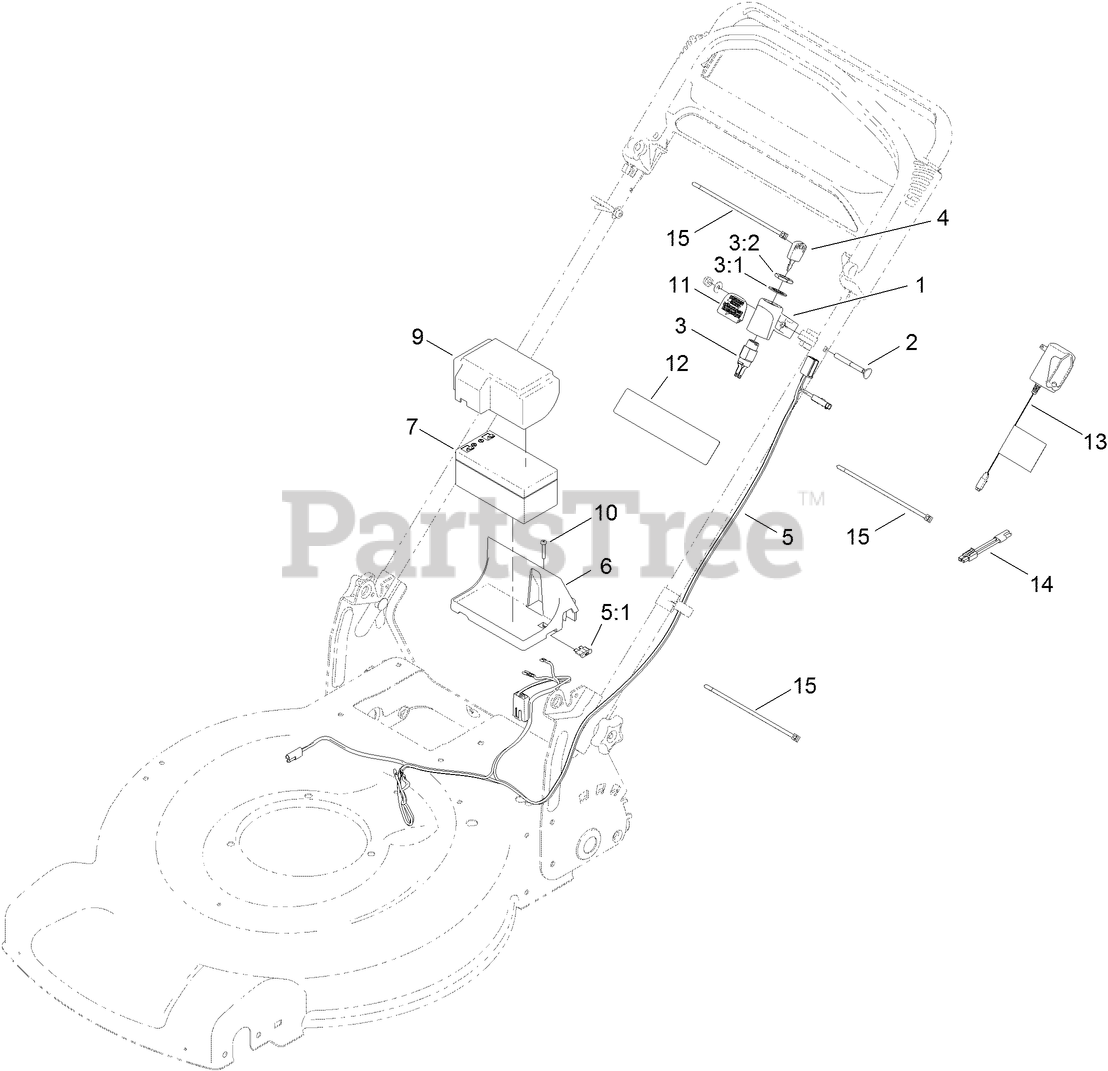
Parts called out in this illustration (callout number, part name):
1	MOUNT-SWITCH
2	SCREW-HANDLE
3	STARTER SWITCH ASM
3:1	WASHER-LOCK
3:2	NUT-HH
5	HARNESS-WIRE
5:1	FUSE-40 AMP
6	TRAY-BATTERY
7	BATTERY-WET
9	COVER-BATTERY
10	SCREW-PPH, PLASTITE
11	DECAL-ELECTRIC START
12	DECAL-WARNING
13	CHARGER-EUROPEAN, 12V DC
14	ADAPTER-CHARGER
15	TIE-CABLE
